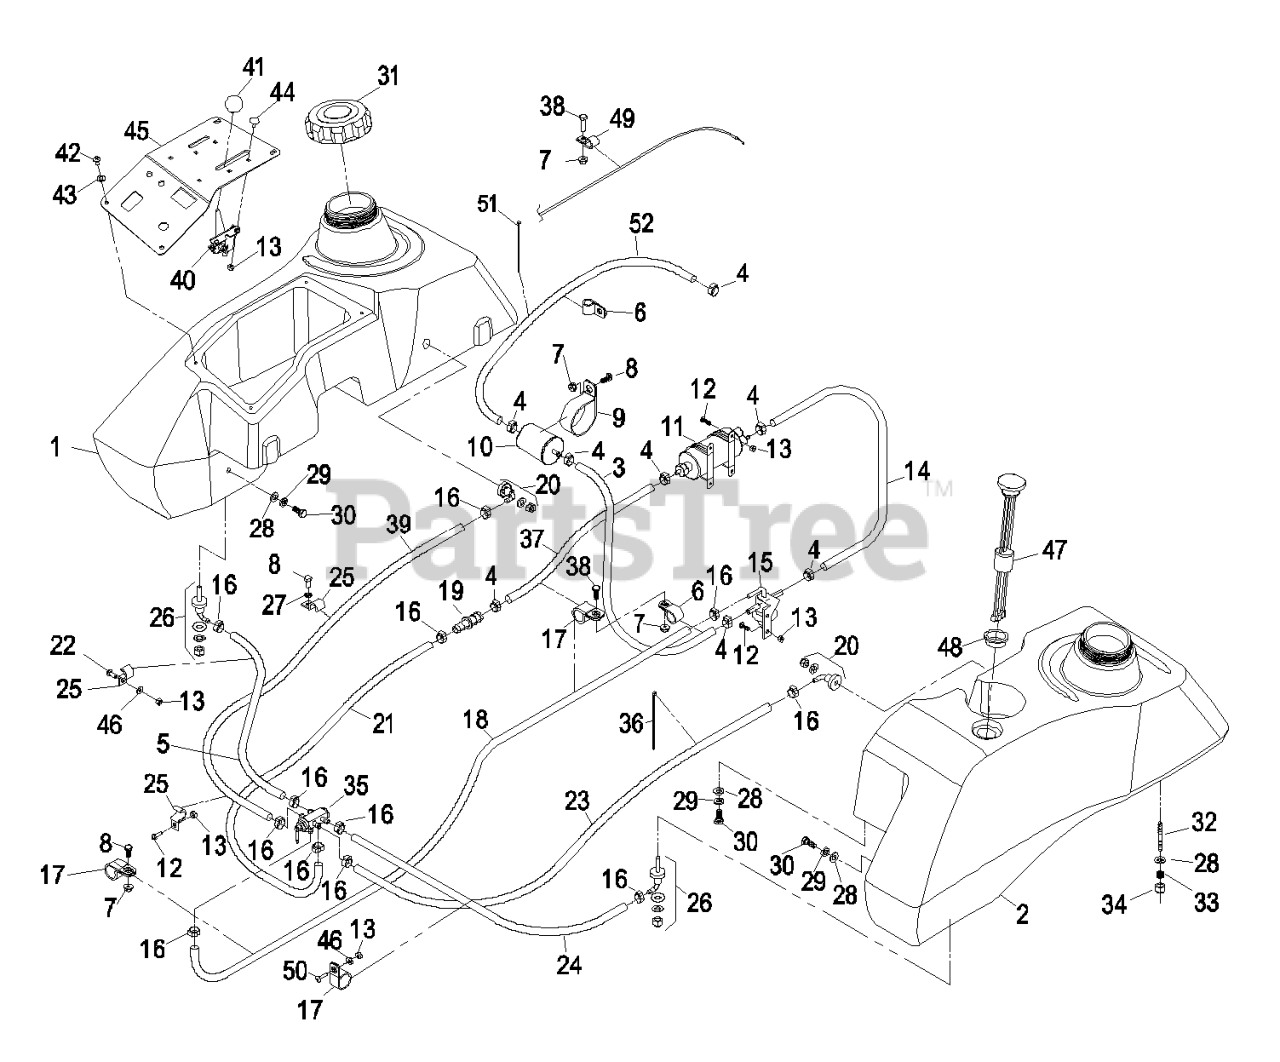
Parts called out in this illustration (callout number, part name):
4	CLAMP-HOSE, FUEL
6	CLIP-LOOM
8	SCREW-HH
9	CLIP-LOOM
10	Kohler Part No. 24 050 03 Fuel Filter (Large)
11	Kohler Part No. 393 20 Fuel Pump
12	SCREW-PPH
13	NUT-LOCK, NI
15	Kohler Part No. 24 403 17 Fuel Regulator
16	CLAMP-HOSE, FUEL
17	CLIP-LOOM
19	CONNECTOR
20	FITTING-FUEL, BULKHEAD
21	HOSE-FUEL
22	BOLT-CARR
24	HOSE-FUEL
25	CLIP-HALF, LOOM
26	FITTING-FUEL, BULKHEAD
27	WASHER-LOCK
28	WASHER-PLAIN
29	WASHER-LOCK
30	SCREW-HH
32	STUD
33	SPRING-TANK, FUEL
34	NUT-LOCK, NI
35	VALVE-FUEL, DUAL FLOW
36	TIE-CABLE
37	HOSE-FUEL
38	SCREW-HH
40	CABLE-THROTTLE
41	KNOB-BALL
42	SCREW-PTH
43	WASHER-SPRING
44	BOLT-CARR
46	WASHER-FLAT
48	CONTACT ORDER SERVICES
49	CLIP-LOOM
50	SCREW-HEAD, TRUSS
51	TIE-PLASTIC
